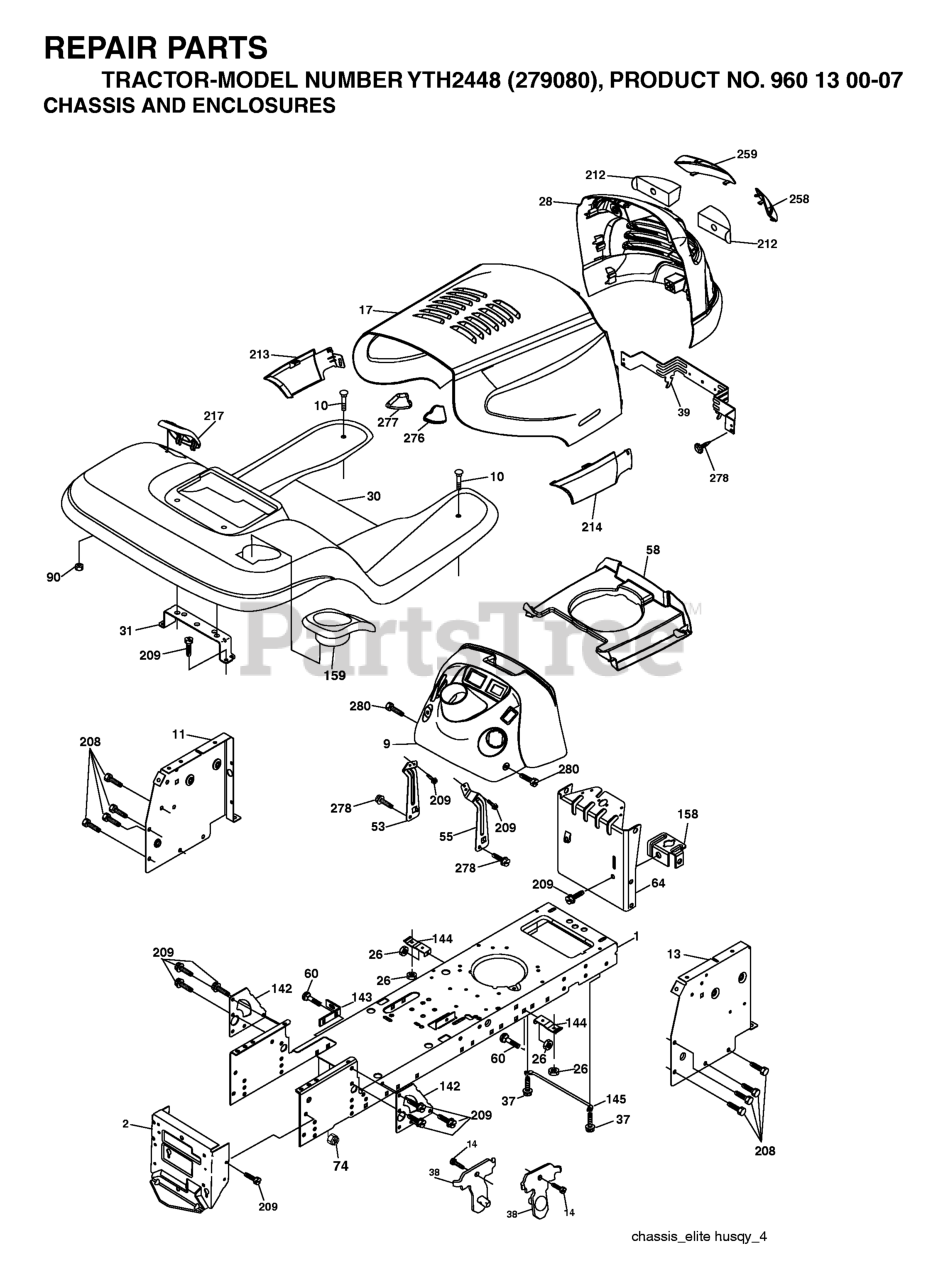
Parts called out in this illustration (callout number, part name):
1	CHASSIS STAMPING
2	DRAWBAR, 12GA
9	DASH
10	BOLT D
11	PANEL.DASH.LH.LTX
26	NUT
30	FENDER
31	BRACKET.SUPPORT.FENDER
37	Screw 5/16-18 x 1/2 Hex, Self Tapping 5/16-18 x 1/2
38	BRACKET.ASM.PIVOT.MOWER.REAR
39	BRACKET PIVOT LASER
60	Bolt - Rd. Hd. Sq. Neckiage 3/8 16 x 3/4
64	DASH LOWER
90	NUT.PUSH.3/16
142	PLATE REINFORCEMENT
143	BRACKET, SWAYBAR CHASSIS
144	BRKT, FOOT REST
145	ROD PIVOT CHASSIS/HOOD
154	BRACKET DASH STEALTH(R)
155	BRACKET DASH STEALTH LH
158	BRACKET PARKING BRAKE
159	CUPHOLDER
208	SCREW 3/8-16X1/2
209	SCREW, 3/8-16X3/4
217	CONSOLE FUEL WINDOW
278	SCREW
280	SCREW 3/8-16X1
